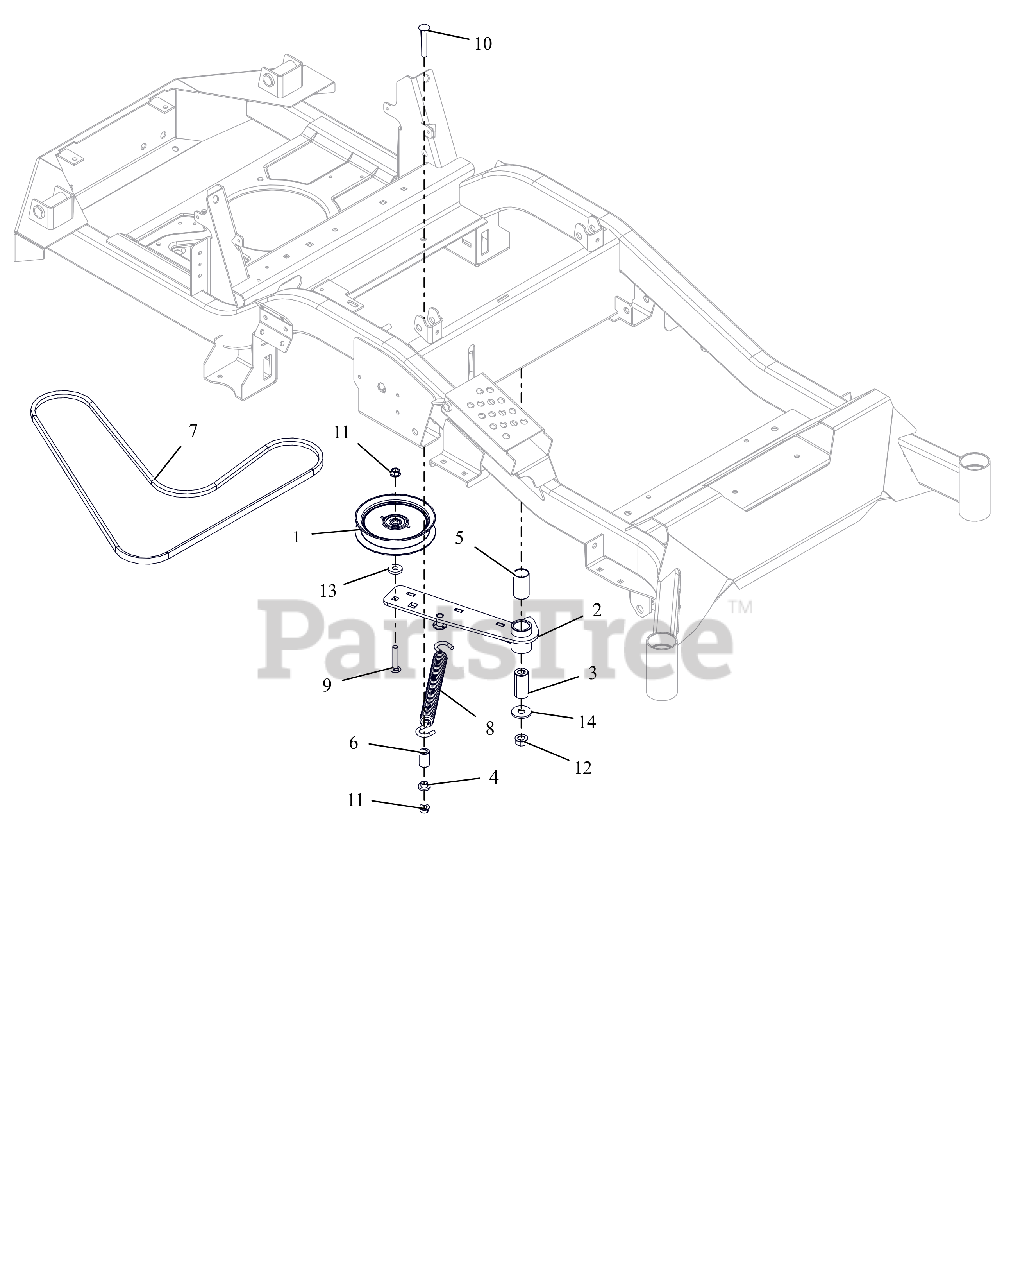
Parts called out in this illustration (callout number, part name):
1	IDLER, FLAT 5.00"
2	WLDMT, HYDRO DRIVE IDLER ARM
3	BSHG, SPCR .502X.997X2.03 PM
4	BSHG-FLG .385X.500X.875X.406
5	BSHG, 1.00X1.125X1.937
6	BUSHING, SLV .380X.750X1.190
7	V-BELT, 4L-WRAPPED
8	SPRING, EXTENSION
9	@BLT-RDHDSQNK .38-16X2.00 G5YZ
10	BLT-RDHDSQSHK, 38-16X2.50 G5YZ
11	@NUT-LK-TOP-FLG .38-16 YWZC
12	@NUT-LK-TOP-FLG .50-13 YWZC
13	WSHR-FL-STL .406X1.00X.188 YWZ
14	WSHR-FL-STL.511X1.441X.125 YWZ
